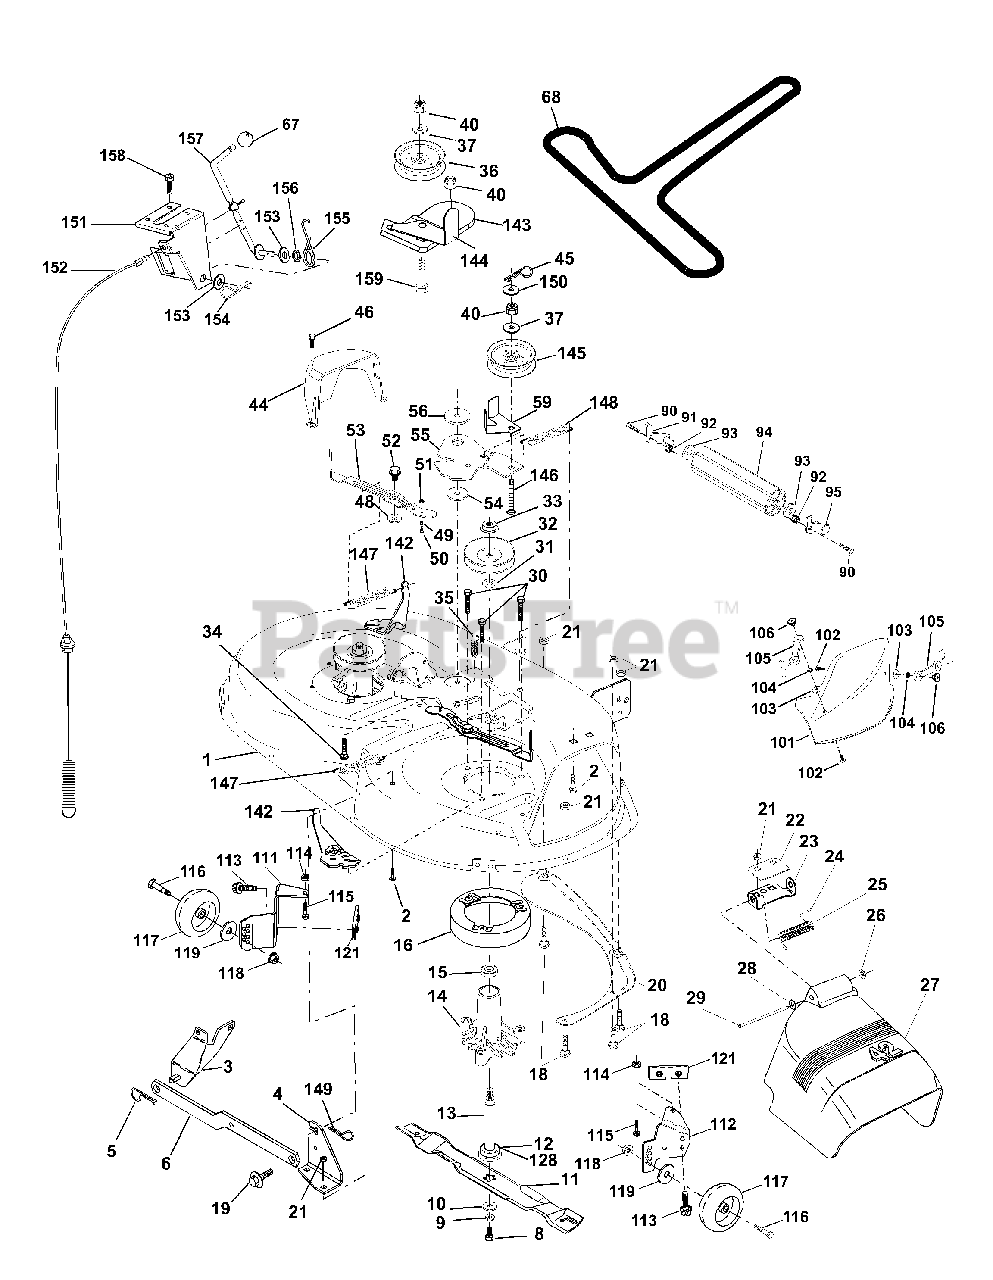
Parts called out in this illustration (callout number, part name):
1	Mower Deck Assembly, 42"
2	Bolt
3	Bracket Asm Fr. Sway Bar 3/42
4	Bracket Asm Deck 42" Sway Bar
5	Retainer Spring
6	Arm, Suspension, Rear
8	Bolt 3/8-24 x 25 Grade 8 patched
9	Washer, Lock
10	Washer,Hardened
11	Blade, Mulching 42" Std
11	Blade Mower 42" Hi-Lift Std
12	Bearing, Ball #6204
13	Shaft Assembly, Mandrel, Vented
14	Housing, Mandrel, Vented
15	Bearing, Ball, Mandrel
16	Stripper, Vented Mower Deck
18	Bolt, Carriage 5/16-18 x 5/8
19	Bolt, Shoulder
20	Baffle, Vortex
21	Nut
22	Stiffener Bracket
23	Bracket, Deflector Mower 42"
24	Cap, Sleeve 80 x 112 Blk Mower
25	Spring, Torsion, Deflector 2 52
26	Nut, Push Phos & Oil
27	Shield, Deflector 42" Blk
28	Washer 11/32 x 5/8 x 16 Gauge
29	Rod, Hinge 42" 6 75 W/G
30	Screw Thdrol Washer Head
31	Washer, Spacer Mower Vented
32	Pulley, Mandrel
33	Nut, Toplock 9/16
34	Bolt
35	Fastener, Christmas Tree
36	Pulley, Idler, Flat
37	Washer 13/32 x 13/16 x 16 Gauge
40	Nut
44	Guard, Mandrel, LH
45	Retainer
46	Screw, Thdrol 1/4-20 x 5/8 T
48	Washer, Hardened
49	Roller Assembly, Cam Follower
50	Bolt, Shoulder #10-24 Grade 5
51	Locknut
52	Bolt, Shoulder 5/16-18 UNC
53	Arm Assembly, Pad, Brake
54	Washer, Hardened
55	Arm, Idler
56	Spacer, Retainer
59	Guard TUV Idler
67	Knob Round
68	V-Belt, 42" Mower
90	Bolt Fin Hex 3/8-16 Unc x 1
91	Bracket Asm Noseroller LH
92	Nut, Lock, Hex W/Ins 3/8-16 UNC
93	Washer 17/3 x 7/8 x 6 Ga.
94	Roller Nose 38 & 42
95	Bracket Asm Noseroller RH
101	Mulcher Cover
102	Screw
103	Washer, Flat
104	Washer, Lock
105	Latch Assembly
106	Nut, Weld
111	Bracket, Gauge, Wheel LH
112	Bracket, Gauge, Wheel RH
113	Screw 5/16 - 18 x 3/4
114	Nut, Keps 5/16 - 18 UNC
115	Bolt, Carriage 5/16-18 x 1/2
116	Bolt, Shoulder
117	Wheel, Gauge
118	Nut Centerlock 3/8-16
119	Washer 3/8 x 7/8 x 14 Ga.
121	Bracket, Extruded
128	Washer, Felt
142	Arm Spring Brake Mower
143	Bracket Arm Idler 42"
144	Keeper Belt 42" Clutch Cable
145	Pulley Idler Flat
146	Bolt Carriage Idler
147	Spring Extension
148	Spring Return Idler
149	Retainer Spring Yellow
150	Washer 9/32 x 3/4 x 16 Ga.
151	Bracket Clutch Cable
152	Clutch Cable 42"
153	Washer Flat 3/8" Type B
154	Spring Retainer
155	Spring Retention LVR CLTCH CAB
156	Spacer Clutch Cable
157	Rod Clutch Cable 3/8"
158	Screw Hex Thd Cut 1/4-20 x 5/8
159	Bolt Rdhd Sqn 3/8-16 UNC x 1-3/4
